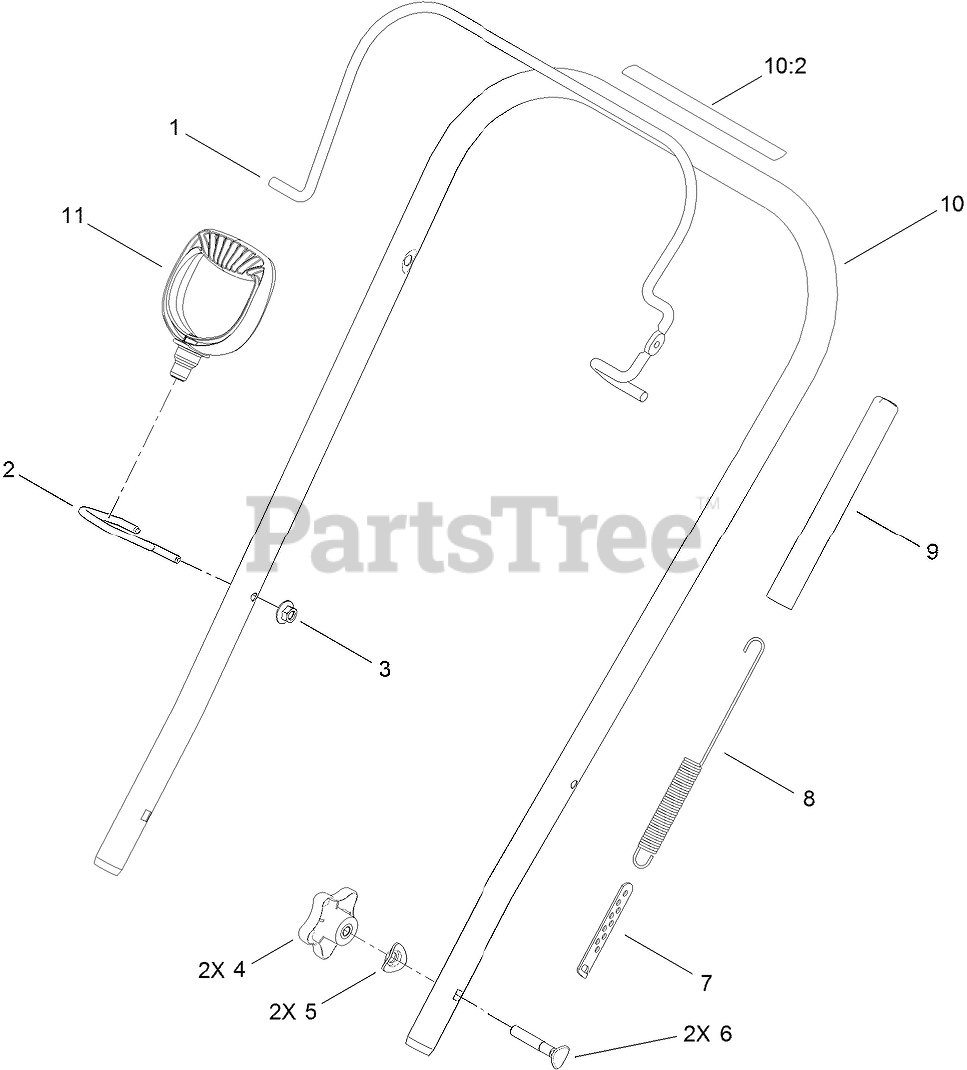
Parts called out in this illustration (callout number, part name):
1	BAIL-CLUTCH
2	GUIDE-ROPE
3	NUT-HEX FLG
4	KNOB-HANDLE
5	WASHER
6	SCREW-HANDLE
7	ADJUSTER-CABLE, CLUTCH
8	SPRING-CLUTCH
9	COVER-SPRING
10	UPPER HANDLE ASM
10:2	DECAL-SAFETY
11	HANDLE-RECOIL
